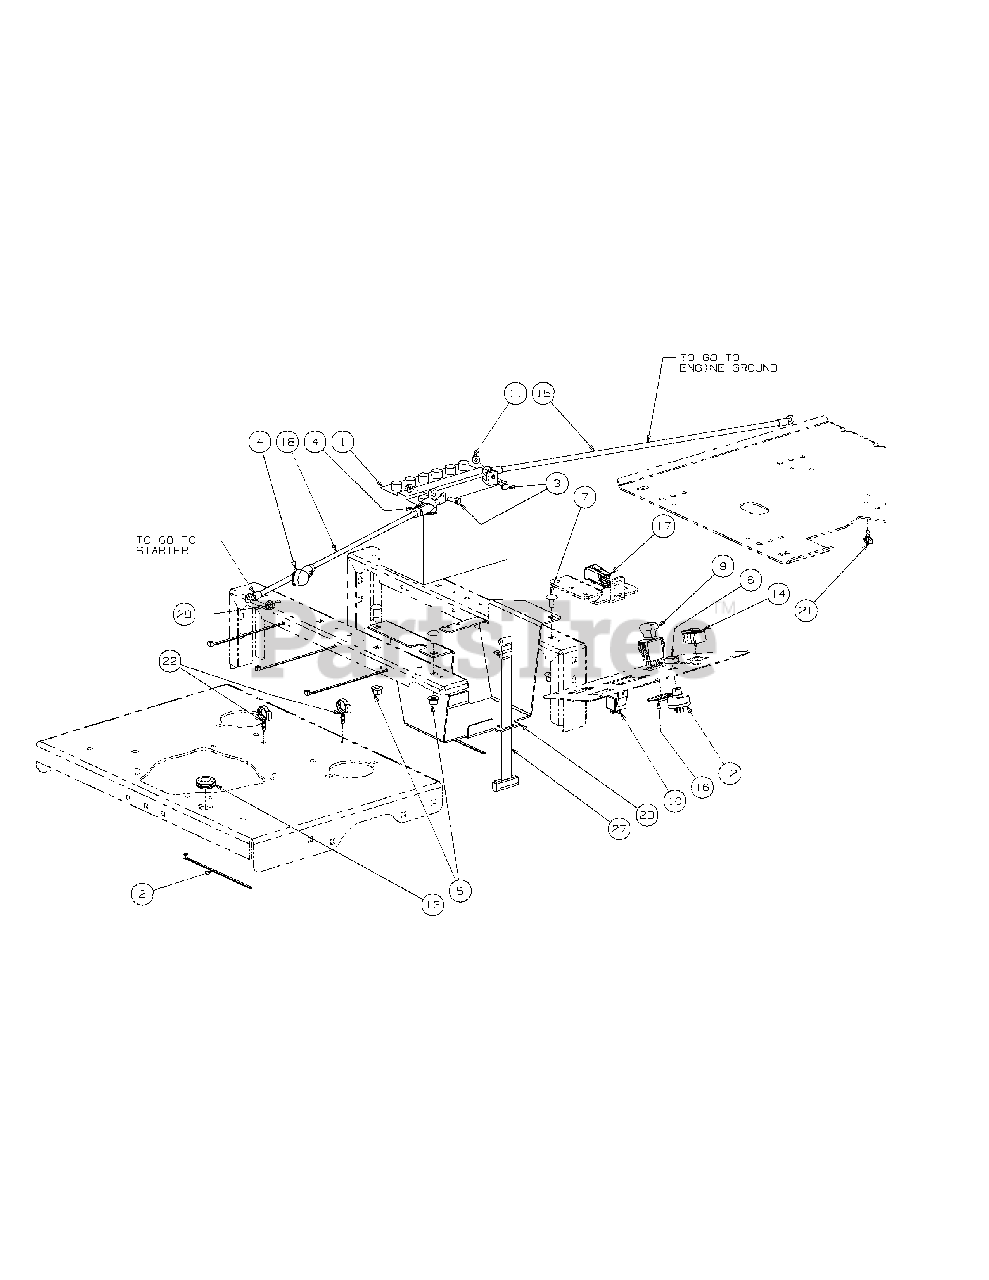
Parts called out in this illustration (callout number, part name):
1	Battery, 12V 225CCA 30 Min
2	Tie, Cable, 3/16 x .05 x 7.4"
3	Screw, Hex, Cap, 1/4-20 x .75
4	Boot, 1" OD Rubber Battery-PST, Red
5	Hex Nut, Flange Lock, 3/8-16
6	Nut, W/Cap, 5/8-32 Ignition
7	Carriage Bolt, 3/8-16 x .75 Long
9	Switch, Electric, PTO
10	Relay, 12V 40A
11	Hex Flange Lock Nut, 1/4-20
12	Switch, Ignition, 6 Pin includes:
13	Grommet, .75 ID
14	Meter, Hour includes:
15	Cable, Battery Red, 34"
16	Bracket, PTO Switch Retainer
17	Switch, Safety N.O./N.C.
18	Cable, Battery Red, 42"
21	Electrical Conduit Clip, 3/8
22	Electrical Conduit Clip, 5/8
23	Battery Bracket
27	Strap, Battery
28	Nut, Hex Flange Whiz
